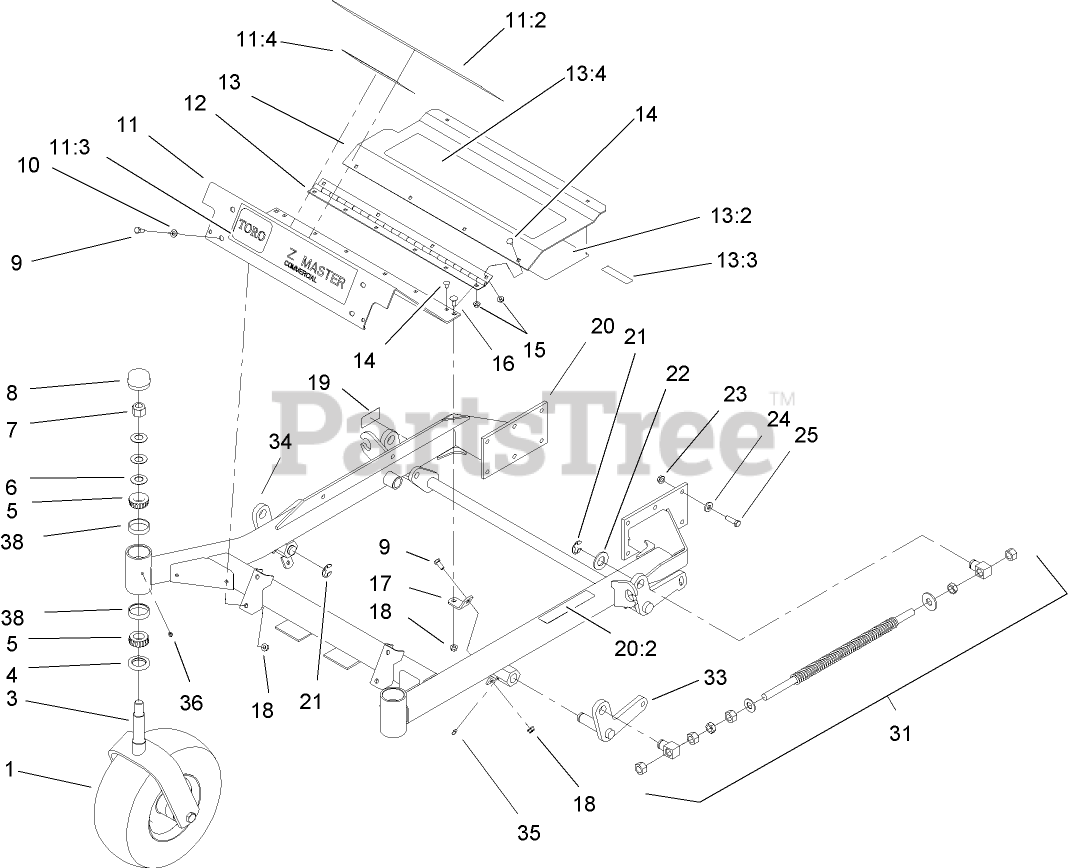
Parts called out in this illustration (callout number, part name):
1	CASTER WHEEL ASM
3	CASTER
4	SEAL-GREASE
5	BEARING-CONE, TAPERED
6	WASHER-BELLVILLE
7	NUT-LOCK, NI
8	CAP-GREASE
9	SCREW-HH
10	WASHER-PLAIN
11	FLOORPAN ASM
11:2	PAD-ANTISKID
11:4	DECAL-WARNING
12	HINGE-FLOORPAN
13	FOOTREST ASM
13:2	DECAL-SERVICE
13:3	DECAL-COVER, MISSING
13:4	PAD-ANTISKID
14	SCREW-CARR
15	NUT-HF
16	BOLT-CARR
17	BRACKET-FLOORPAN
18	NUT-HF
19	DECAL-STD, SAFETY
20	FRONT FRAME ASM
20:2	DECAL-WARNING
21	RING-RETAINING, EXT
22	WASHER-FLAT
23	NUT-HHF, WHIZ
24	WASHER-BELLEVILLE
25	SCREW-HH
31	Front Spring ASM
33	LH FRONT DECK LIFT ASM
34	RH FRONT DECK LIFT ASM
35	FITTING-GREASE
38	BEARING-CUP, TAPERED
